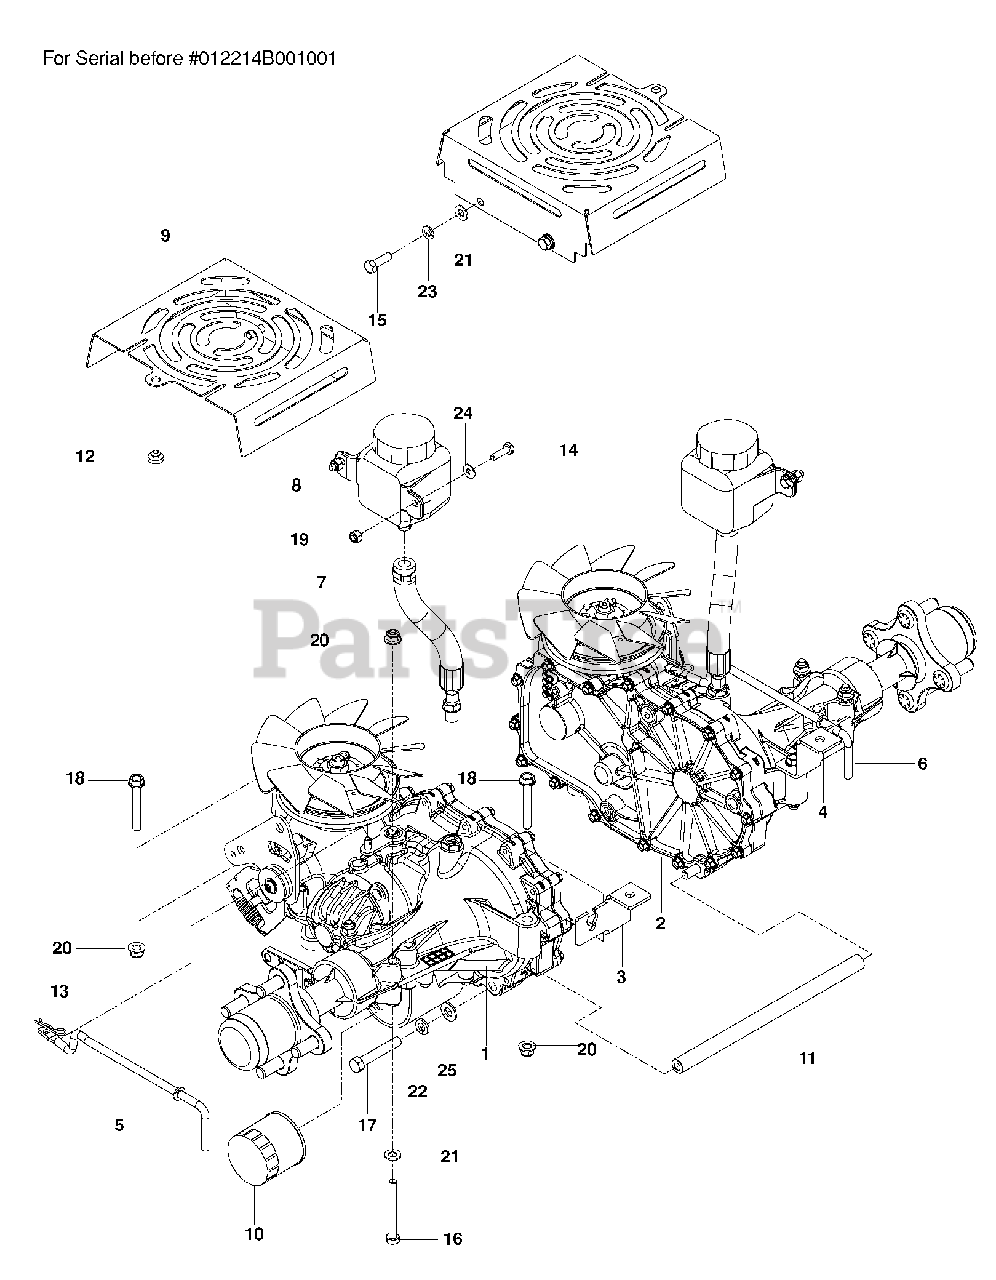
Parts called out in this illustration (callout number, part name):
1	HG_TRANS ZT-3100 LT
2	HG_TRANS ZT-3100 RT
5	LINKAGE, LEFT BYPASS
6	LINKAGE, RIGHT BYPASS
7	HOSE ASSY, EXPANSION
8	HG_TANK, EXPANSION, 350ML
9	SHIELD, FAN, BLK
10	HG_FILTER, ZT4800
11	TUBE, SPACER, 3400
12	GROMMET, BUMPER
13	HAIRPIN #2
14	HCS 1/4-20X7/8 GR5
15	HCS 5/16C X 1
16	HCS 5/16C X 2-3/4
17	HCS 3/8-16X2-1/4 LOC PATCH GR8
18	HHFS 5/16-18 X 2.25 GD 5
19	NUT 1/4-20 NYLOC
20	5/16-18 NYLOC FLANGE NUT
21	FLAT WASHER 5/16 SAE
22	SLW 3/8 STD
23	WASHER 5/16 LOCK
24	WASHER 1/4 SAE
25	WASHER 3/8 SAE FLAT
